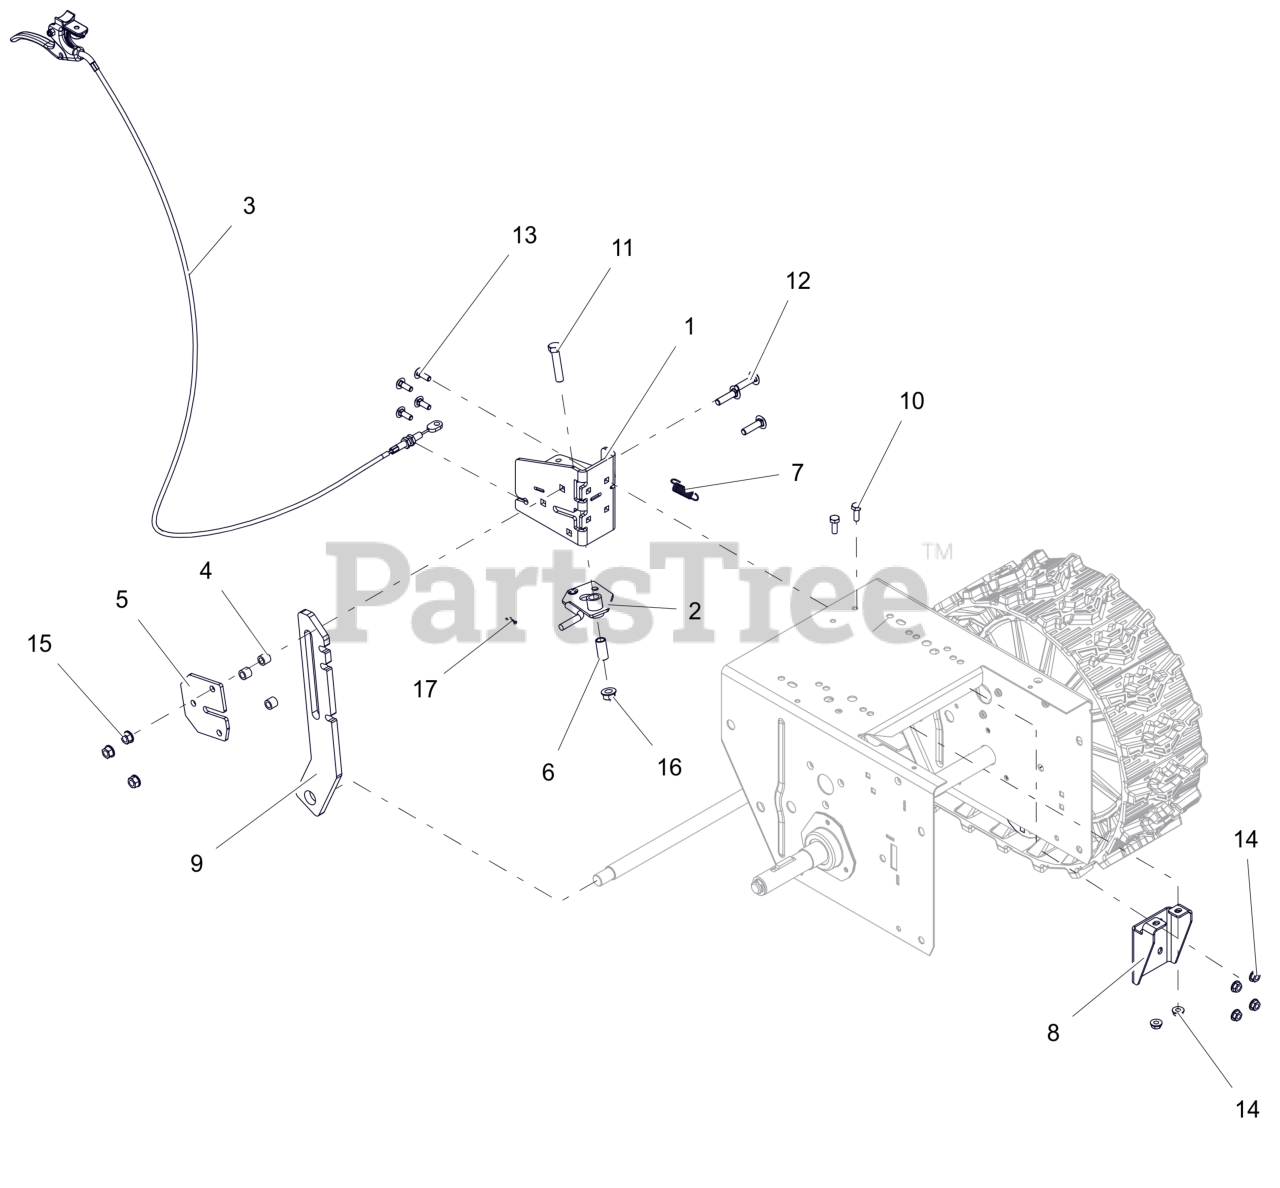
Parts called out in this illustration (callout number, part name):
1	BRACKET,HEIGHT ADJUSTER-DELUXE
2	LOCK,HEIGHT ADJUSTER TRIGGER
3	CABLE, TRACK REMOTE
4	SPACER .50 X .32 X .42
5	PLATE, HEIGHT ADJUSTER
6	BSHG-SLV .385X.500X1.045
7	SPRING-EXT .047 X .438 X 1.85
8	BRACKET, REINFORCEMENT
9	ADJUSTER, HEIGHT-DELUXE BWT
10	BLT, HEX .25-20X.75 G5 ZCC
11	BLT, HEX .38-16X1.75 G5 ZCC
12	BLT, RHSSN.31-18X1.25 G5 ZCC
13	BLT, RHSN .25-20X.750 G5 ZCC
14	NUT-LK-CTR-FLG .25-20 ZC120
15	NUT-LK-TOP-FLG .312-18 GF ZCC
16	NUT-LK-CTR-FLG .375-16 GF ZCC
17	PIN, HAIR #178 .06X.77 ZCC
